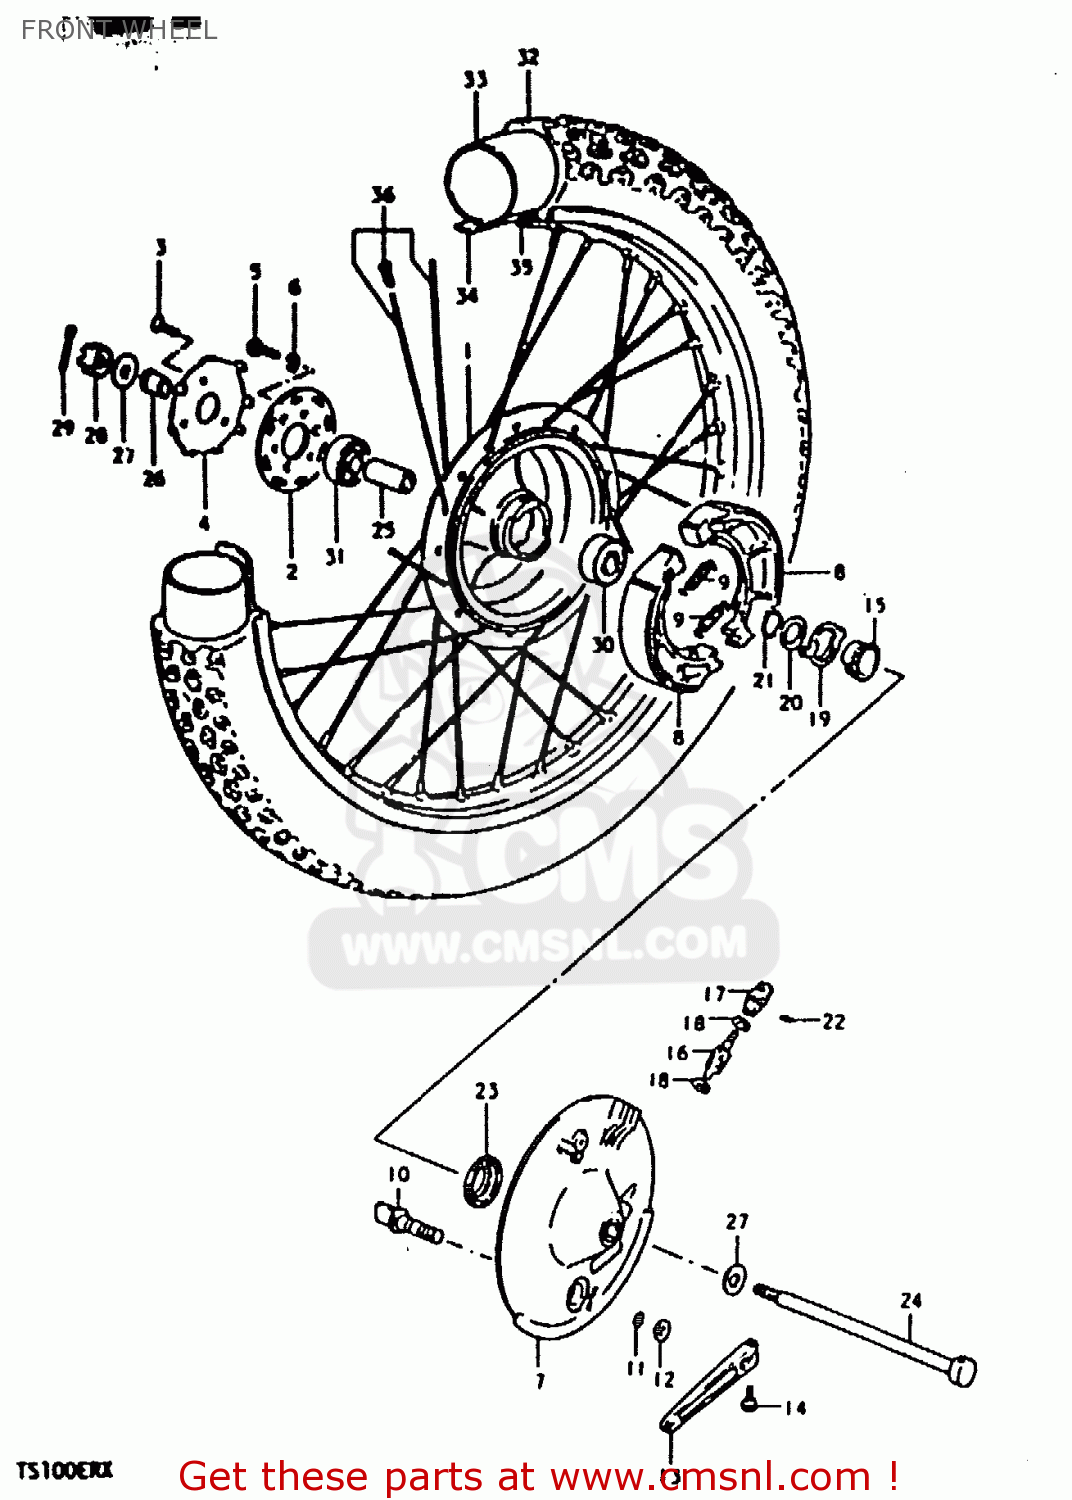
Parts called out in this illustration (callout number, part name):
1	HUB,FR WHEEL
2	FLANGE,FR HUB,R
3	SCREW
4	RETAINER,FR HUB BEARING,R
5	BOLT, UPPER
6	LOCK WASHER
7	PANEL,FRONT HUB
8	SHOE,BRAKE
9	SPRING(L:34)
10	CAM,FRONT BRAKE
11	O-RING (D:2.4 ID:13.8)
12	WASHER (14.5X22X1.6)
13	LEVER,FRONT BRAKE CAM
14	BOLT
15	GEAR,SPEEDOMETER
16	PINION,SPEEDOMETER
17	BUSH,METER GEAR OUTER
18	WASHER (5.1X9X0.4)
19	DRIVER,SPEEDOMETER GEAR
20	WASHER(18.5X24X1)
21	CIRCLIP
22	SCREW
23	OIL SEAL (43X58X7)
24	AXLE,FRONT
25	SPACER (12.6X19X52)
26	SPACER,FR AXLE,R
27	WASHER
28	NUT 12MM
29	COTTER PIN
30	BEARING
31	BEARING, RH
32	TIRE,FRONT
33	TUBE 2.75-19 070-483MM
34	PROTECTOR,WHEEL,INNER
35	RIM,FR WHEEL
36	SPOKE SET,FRONT
